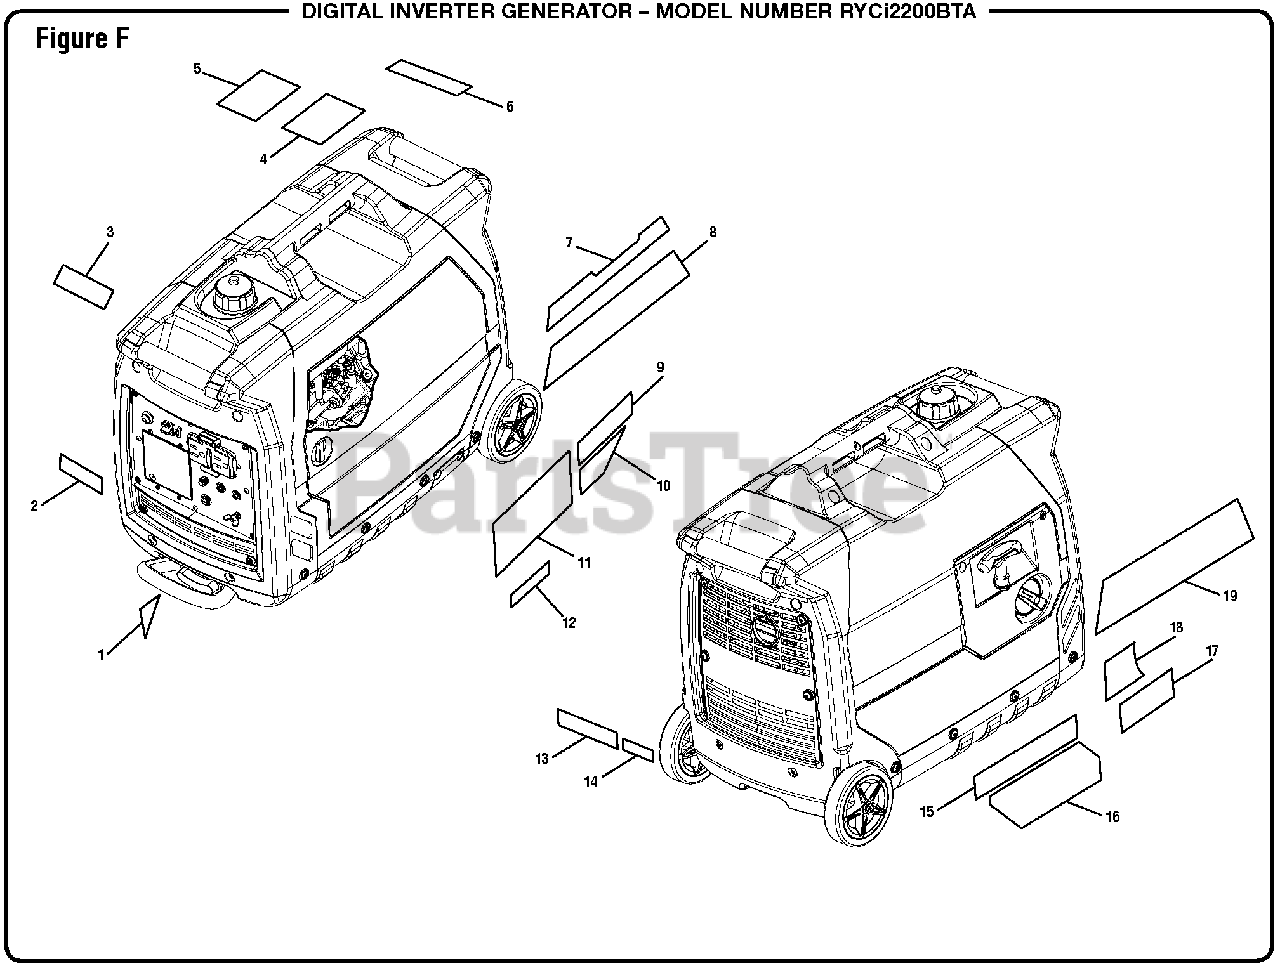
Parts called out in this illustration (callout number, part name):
1	Handle Release Label
2	Logo Label
3	Fuel Stabilizer Label
4	CPSC Label
5	Danger Label
6	Ground Warning Label (English/French)
7	Fire Distance Label
8	Performance Label (Maintenance Door)
9	Inquiries Label
10	Lubricant Label
11	Maintenance Door Label
12	Maintenance Label
13	Combustion Label
14	Hot Surface Label
15	Start Label
16	Gen Control/Bluetooth Label
17	Easy Start Logo Label
18	Choke Label
19	Performance Label
